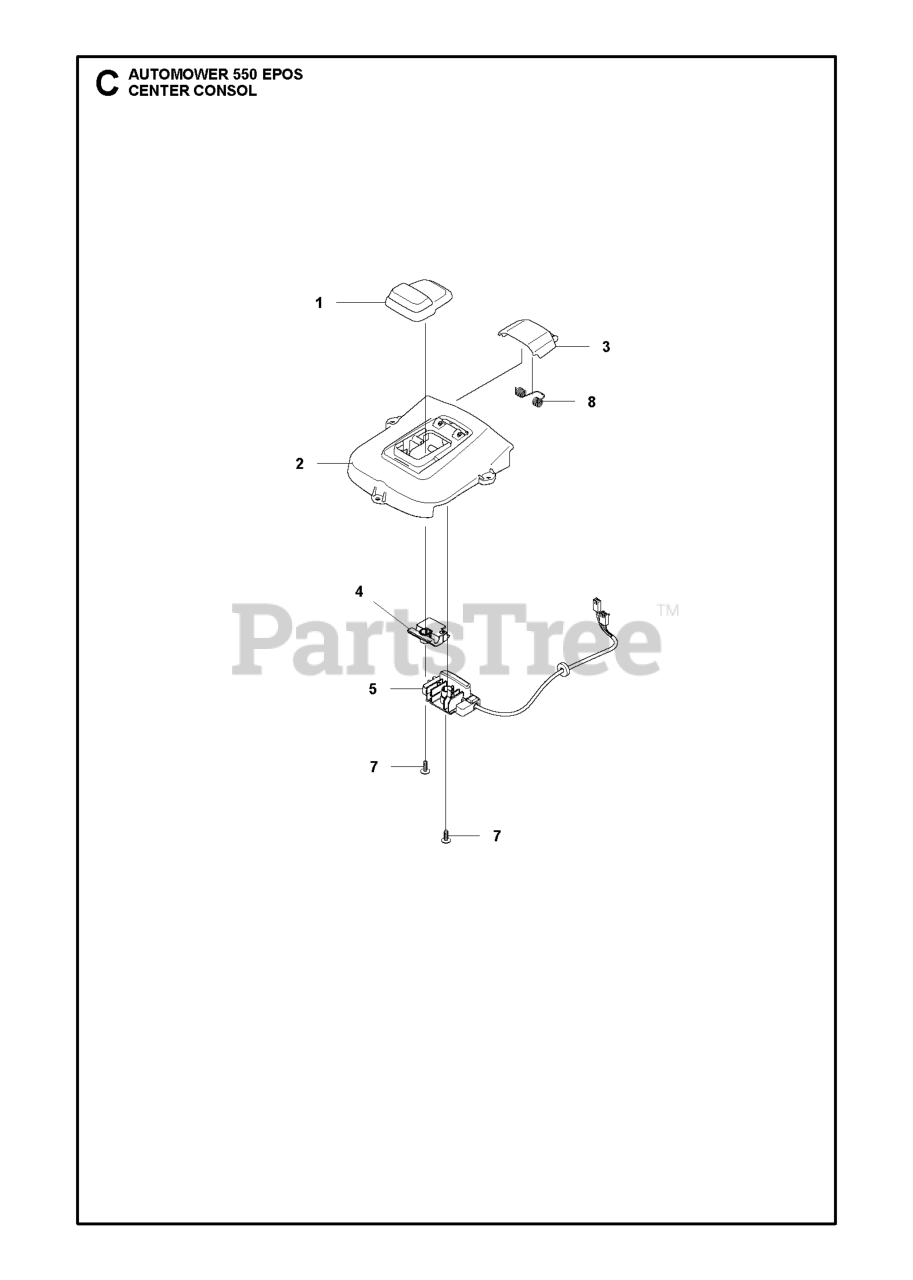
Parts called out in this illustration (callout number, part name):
1	BUTTON START / STOP
2	CONSOLE REAR
3	LID START/STOP BUTTON TRANSPAR
4	SUPPORT BUTTON
5	HOUSING ASSY RGB LED LIGHT
7	SCREW 14MM
8	SPRING LID
